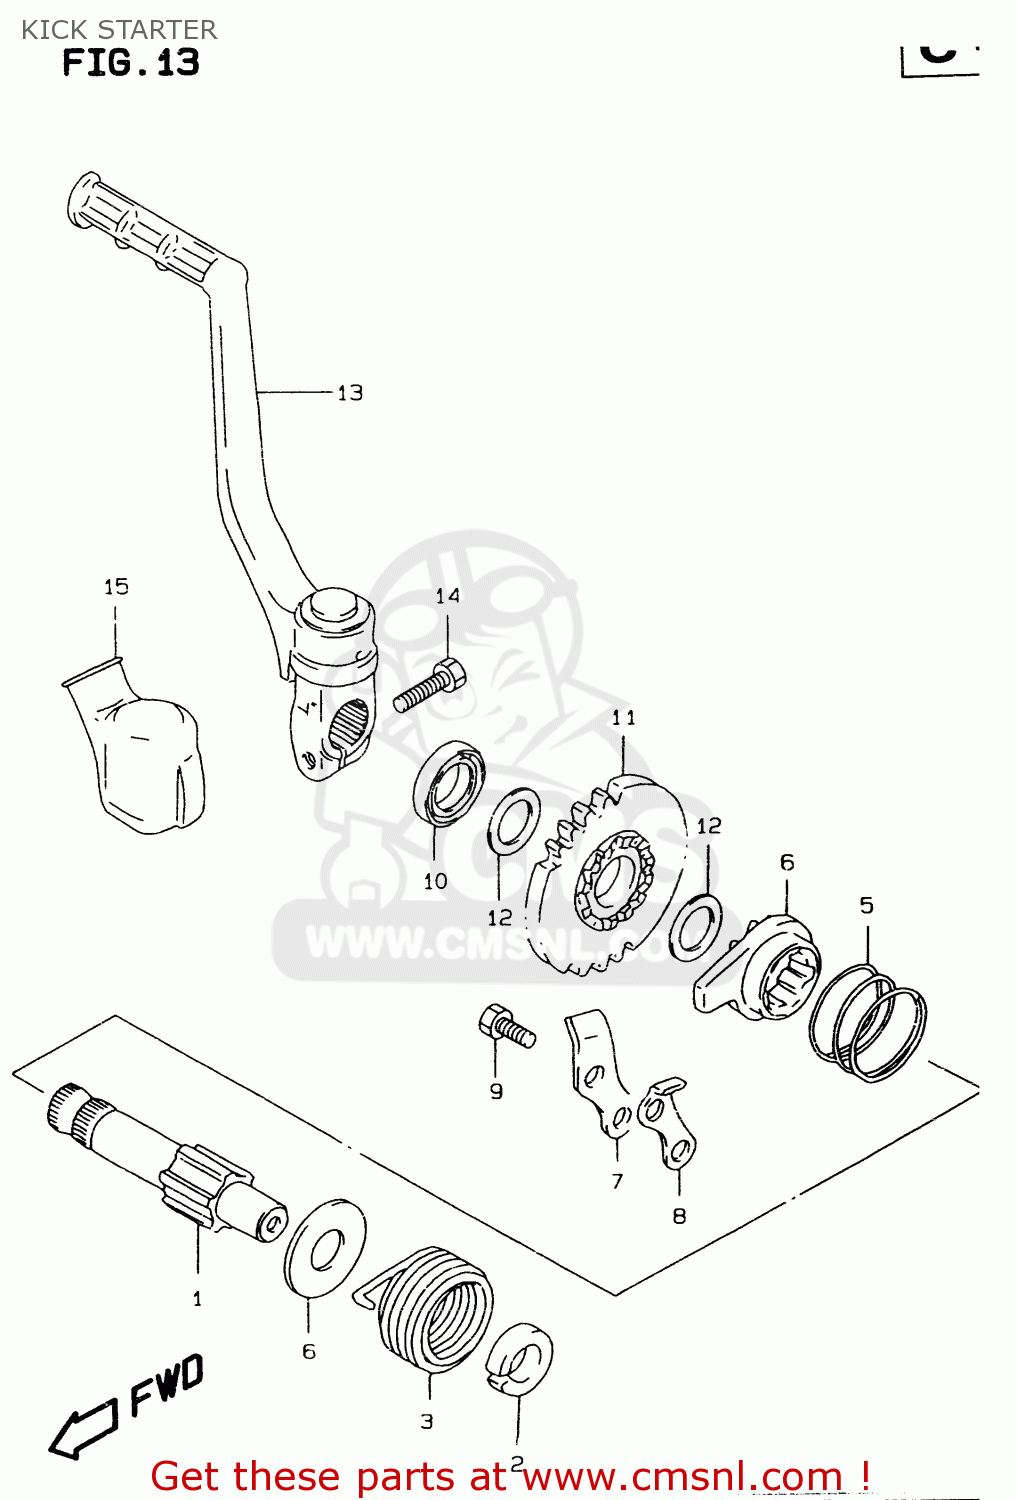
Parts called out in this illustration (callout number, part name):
1	SHAFT,KICK STARTER
2	GUIDE,SPRING
3	SPRING
4	STARTER,KICK
5	SPRING
6	WASHER
7	GUIDE,KICK STARTER
8	STOPPER,KICK STARTER
9	BOLT
10	SEAL,OIL(14X24X6)
11	GEAR,KICK STARTER DRIVE
12	WASHER
13	LEVER ASSY,KICK STARTER
14	BOLT
15	COVER,KICK LEVER JOINT
